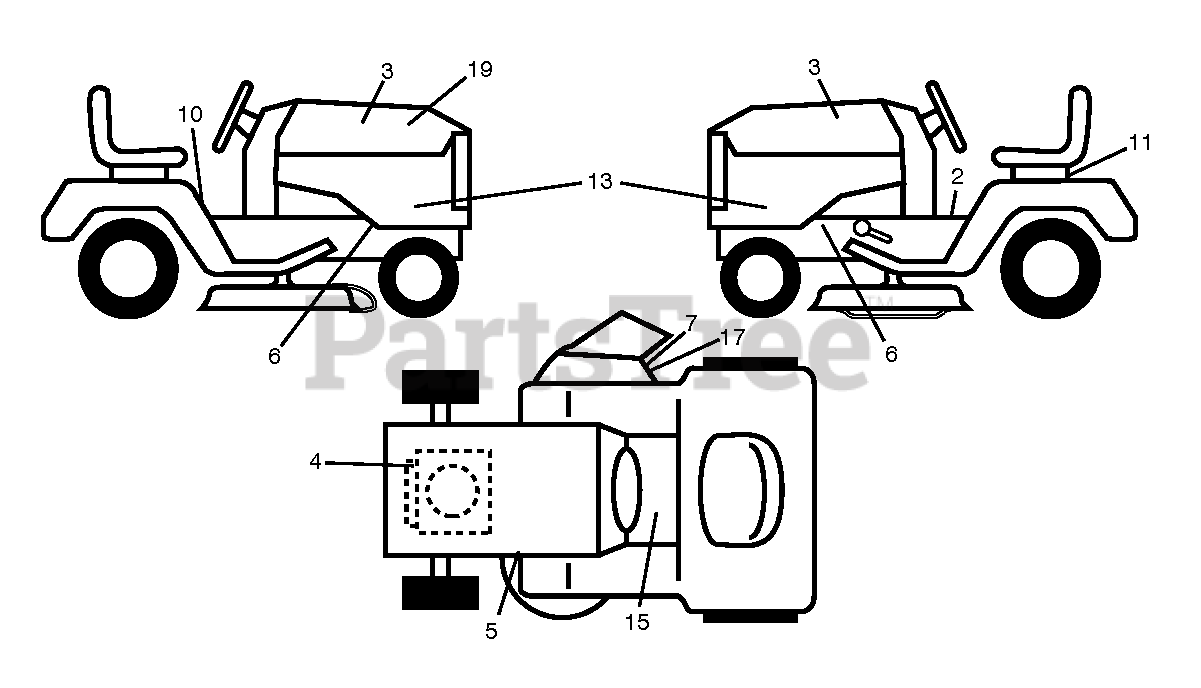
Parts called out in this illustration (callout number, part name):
2	DECAL.PARKING.BRAKE.SADDLE.LT
3	DECAL.BADGE.170MM.TEXTLOGO.
4	DECAL.ENGINE.WARNING
5	DECAL.V-BELT.SCH.42/46"MEC/ELE
6	DECAL.CHASSIS.HOT.MUFFLER
7	DECAL.CUTFINGER.CE.02
10	DECAL.READ.OWN.MAN.SYMBOL.LT
11	DECAL BTRY SYMBOLS
13	DECAL.SDPNL.LTH2142DR.2012.HUS
15	DECAL.FNDR.SDLE.BRAKE.CLUTCH.6
17	DECAL.DFLCTR.WARNNG.CTFNGR.SYM
19	DECAL.RPL.BSM33.END.TLW.42.K46
